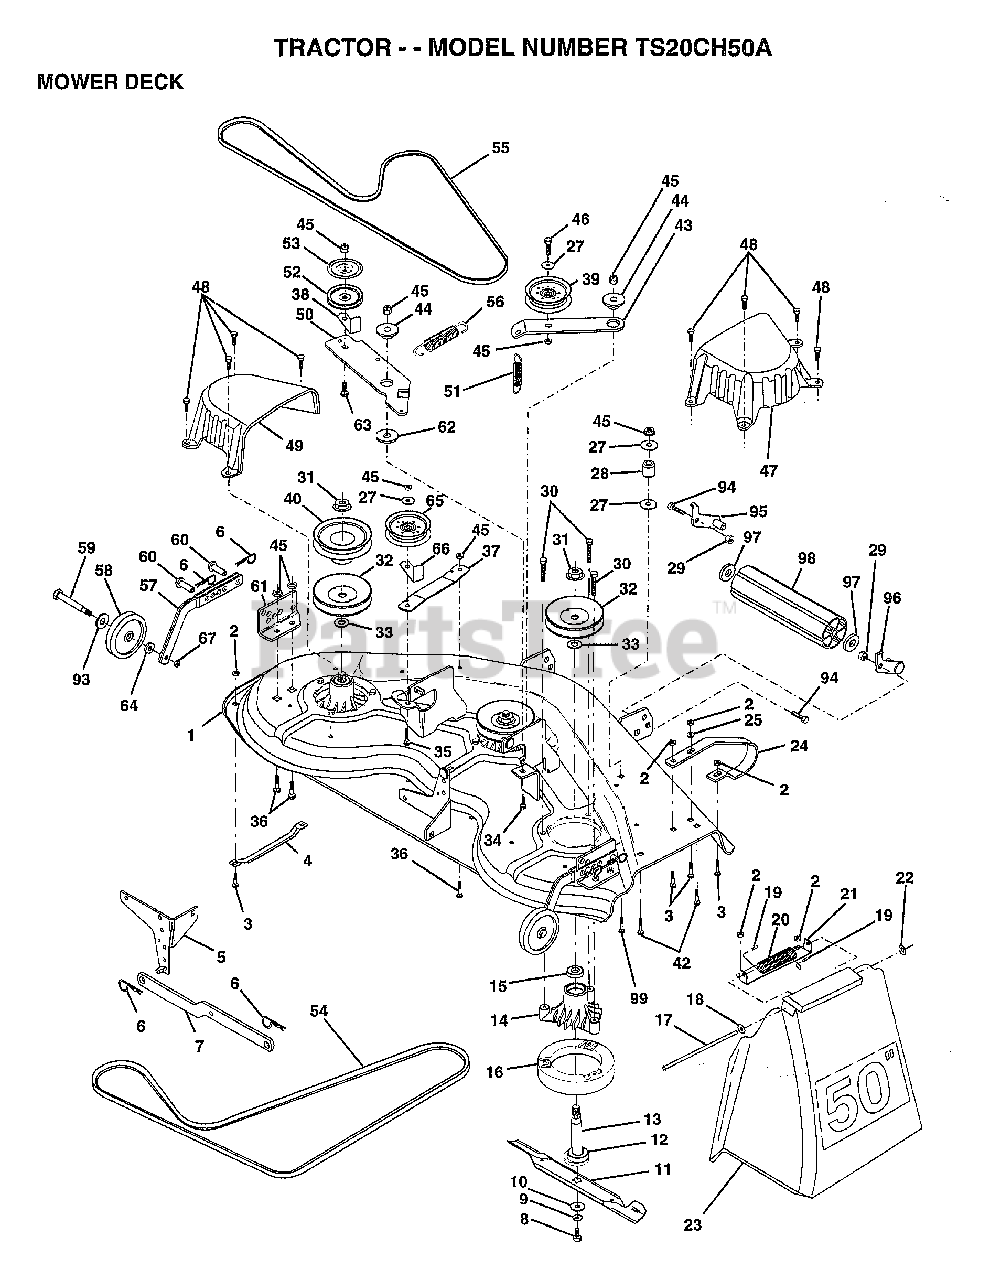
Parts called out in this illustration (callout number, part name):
1	DECK ASM MWR 50VT
4	RUNNER-LH M
5	BRKT.ASM.SW.44/50
8	BLADE BOLT
10	WASHER.HARD.BLADE
11	"BLADE.50"" HD"
12	BEARING.BALL
13	SHAFT.ASM.W/BRNG
14	HOUSING.MAND.44.V
15	BEARING
16	STRIPPER RND MWR
17	ROD-HINGE T
18	WASHER
19	CAP-SLEEVE LT
20	SPRING TORSION
21	BRKT DEFLECTOR
22	NUT PUSH M
23	DEFLECTOR
24	"RUNNER RH 50"" DK"
25	WASHER M
27	WASHER
29	NUT
33	WASHER
34	BOLT.3/8-14X1.25
35	BOLT
36	BOLT D
37	STIFFENER.ARM.IDL
39	FLAT IDLER PULLEY
40	"PULLEY.DRIVEN.44"""
42	BOLT
43	"ARM.IDLER.SEC.44"""
44	SPACER RETAINER
47	"COVER.MAND.RH.44"""
48	SCREW.1/4-20X5/8
49	COVER.MANDREL.LH
50	ARM.IDLER.PRIMARY
51	"SPRING.SEC.44""VEN"
52	PULLEY.IDLER.VGRO
53	SHIELD.IDLER.44.V
54	BELT V PRIM 50
55	BELT-V.SEC.46.KEL
56	SPRING.EXT.DECK.
57	BAR.ASM.GUAGE.WHL
58	WHEEL.GAGE.BLK.PL
59	BOLT M
60	PIN.CLEVIS
61	BRACKET.GUAGE.WHL
62	HARDENED WASHER
63	BOLT.3/8-16X1.50
64	WASHER
65	IDLER-FLAT T
67	LOCKNUT
93	WASHER
94	BOLT
97	WASHER
99	BOLT
